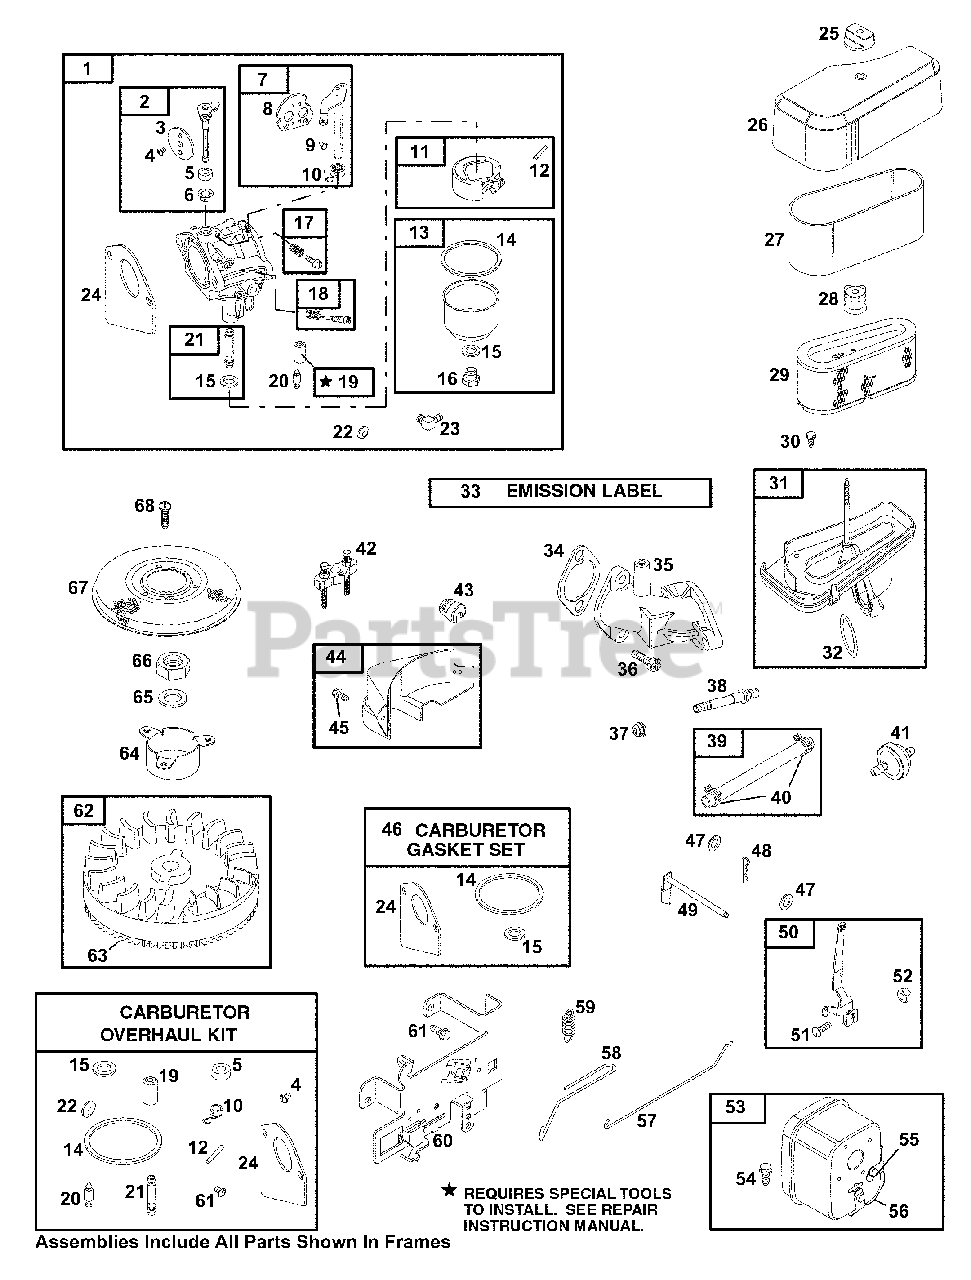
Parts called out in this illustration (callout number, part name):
1	Carburetor
2	Throttle Shaft Kit
3	Throttle Valve
4	Screw (Throttle Valve)
5	Seal-Throttle Shaft
6	Bushing-Throttle Shaft
7	Choke Shaft Kit
8	Valve-Choke
9	Screw (Choke Valve)
10	Spring & Seal Assembly
11	Float-Carburetor
12	Pin-Float Hinge
13	Bowl-Float
14	Gasket-Float Bowl
15	Sealing Washer
16	Screw (Float Bowl)
17	Kit-Idle Speed
18	Kit-Idle Mixture
19	Inlet Seat
20	Float Needle Valve
21	Nozzle-Carburetor
22	Plug-Welch
23	Connector-Hose
24	Intake Gasket
25	Knob-Air Cleaner
26	Cover-Air Cleaner
27	Filter-Pre Cleaner
28	Seal-Air Cleaner Stud
29	Filter-A/C Cartridge
30	Screw (Air Cleaner Base Mounting)
31	Base-Air Cleaner
32	O-Ring Seal (Air Cleaner Base)
33	Label-Emissions
34	Intake Gasket
35	Intake Manifold
36	Screw (Intake Manifold)
37	Nut (Carburetor)
38	Stud (Carburetor)
39	Line-Fuel (Cut to Required Length)
40	Clamp-Hose
41	Filter-Fuel
42	Flywheel Puller
44	Cover-Starter Drive
45	Screw (Starter Drive Cover)
46	Carburetor Gasket Set
47	Washer (Governor Crank)
48	Pin-Cotter
49	Crank-Governor
50	Governor Control Lever
51	Bolt (Governor Control Lever)
52	Nut (Governor Control Lever)
53	Muffler-Exhaust
54	Screw (Muffler Bracket)
55	Screw (Muffler-Exhaust)
56	Shield-Heat
57	Mechanical Governor Link
58	Choke Link
59	Governor Spring
60	Bracket-Control
61	Screw (Control Bracket)
63	Gear-Ring
64	Cup-Flywheel
65	Washer (Flywheel)
66	Nut (Flywheel)
67	Rotating Screen
68	Screw (Rotating Screen)
